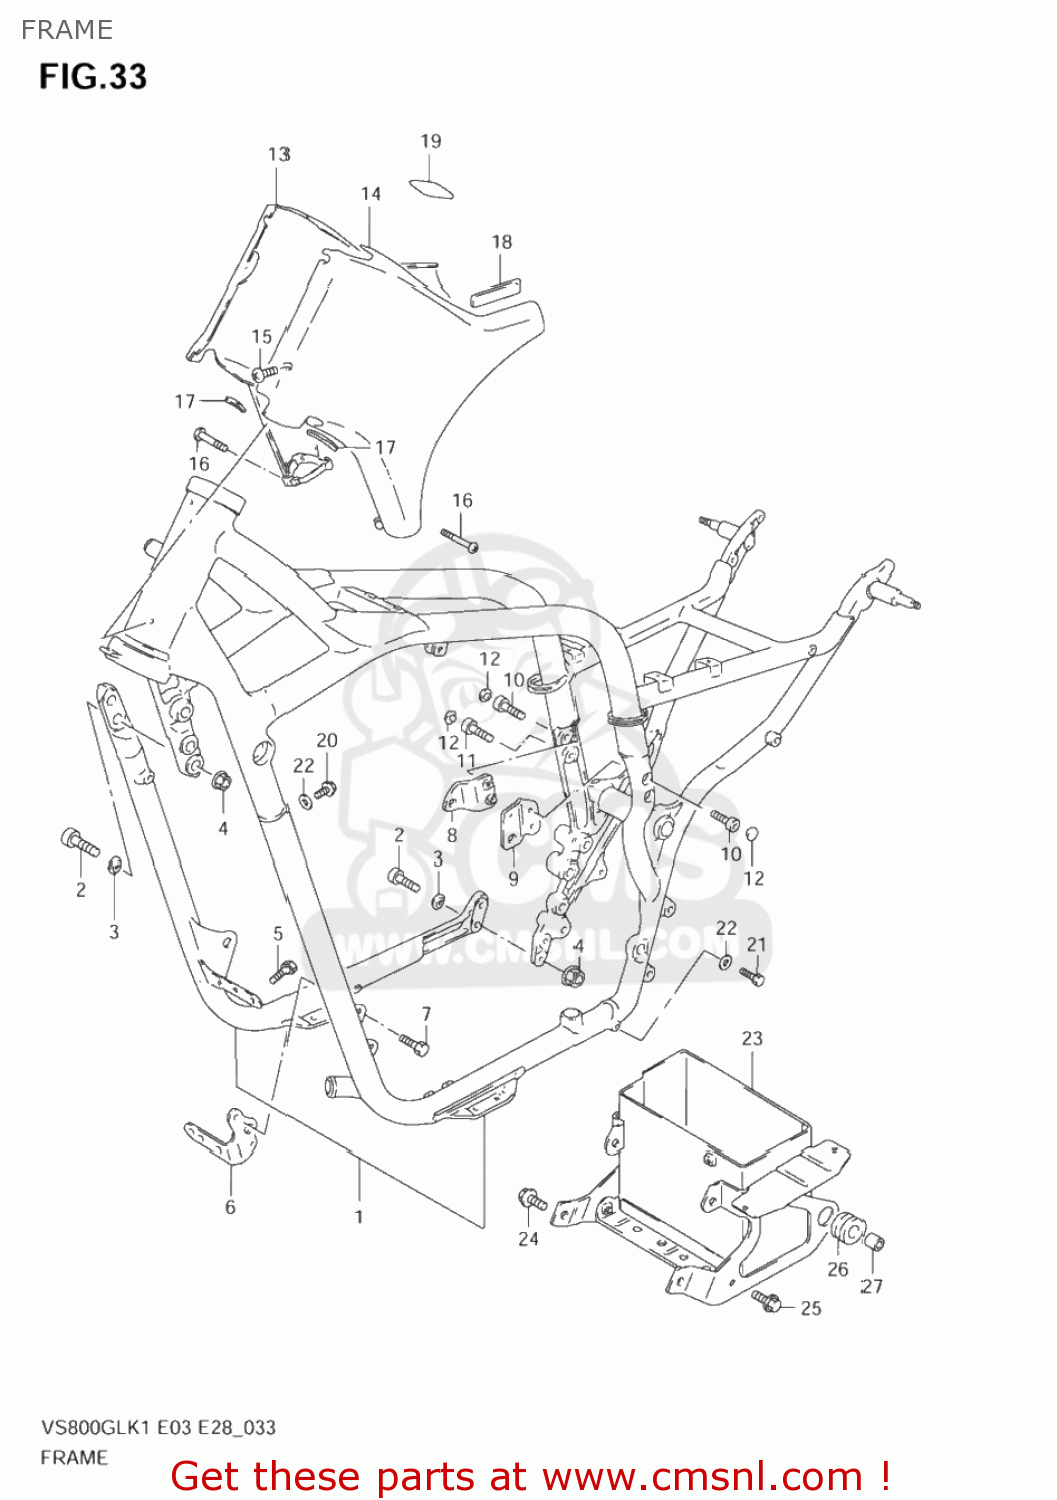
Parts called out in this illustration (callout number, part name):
1	FRAME SET(RED)
2	BOLT(10X33)
3	WASHER
4	NUT
5	BOLT, FRONT
6	PLATE,ENGINE MOUNT NO.1,L
7	BOLT
8	PLATE,ENGINE MOUNT NO.3,R
9	PLATE,ENGINE MOUNT NO.3,L
10	BOLT(8X30)
11	BOLT
12	CAP(OD:14.5)
13	COVER,FRAME HEAD,R(BLACK)
14	COVER,FRAME HEAD,LEFT
15	SCREW 6X10
16	SCREW
17	MOLDING
18	PROTECTOR(80X80X2)
19	TAPE,FRAME HEAD COVER
20	UNION BOLT,AIR VENT
21	BOLT
22	GASKET(6.4X11.5X0.8) (NAS)
23	HOLDER,BATTERY
24	BOLT
25	BOLT
26	CUSHION
27	BUSH
